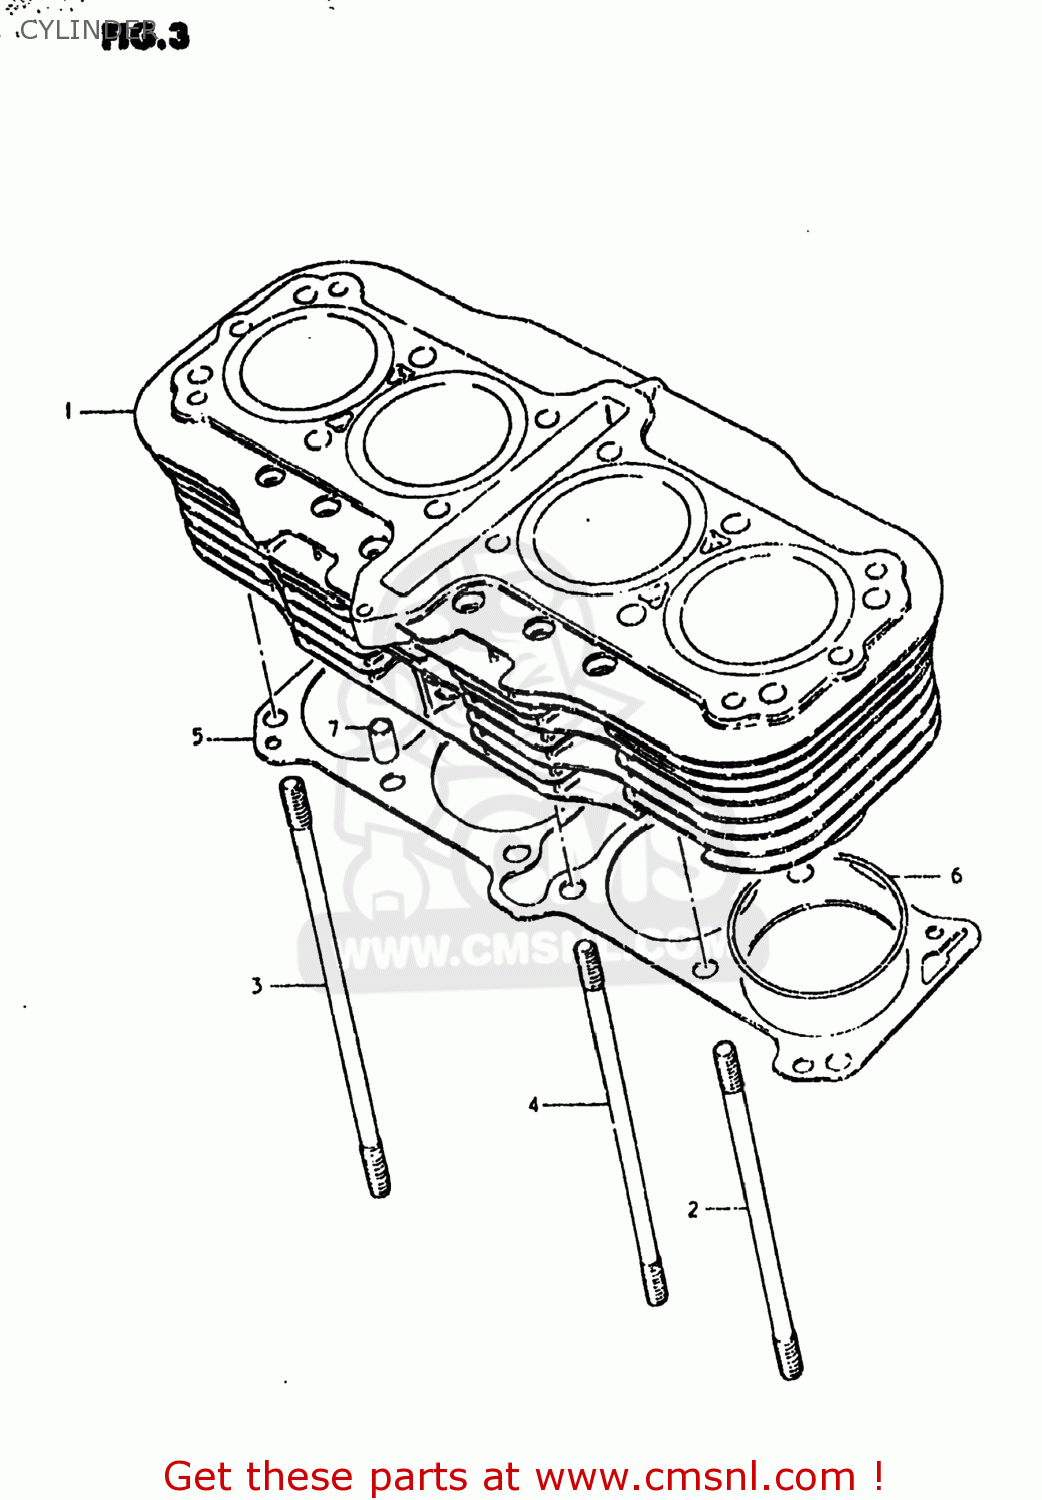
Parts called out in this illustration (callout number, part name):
1	CYLINDER
2	STUD
3	STUD
4	STUD
5	GASKET,CYLINDER (MCA)
6	O RING(D:2,ID:70)
7	PIN
